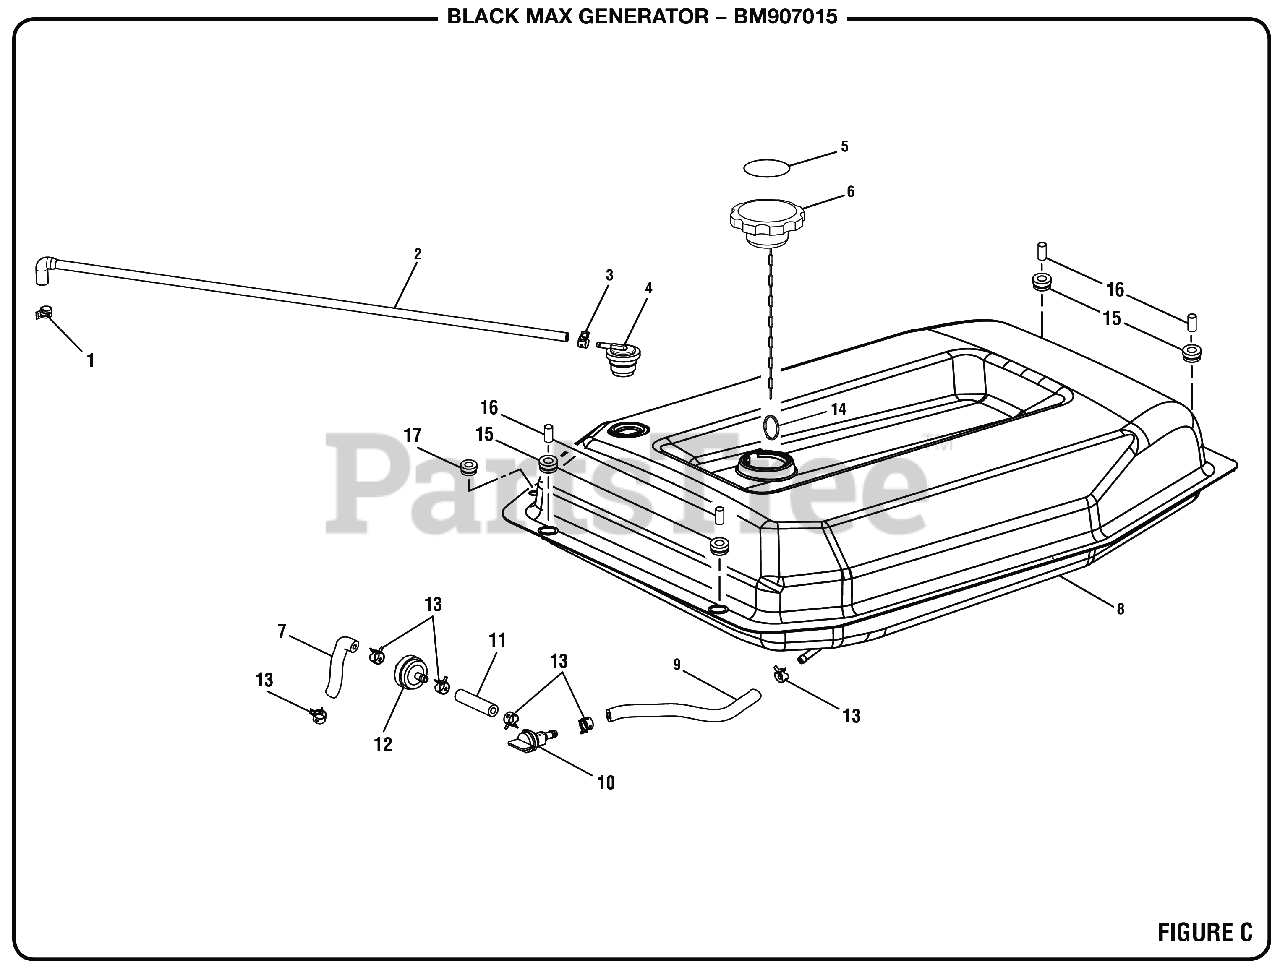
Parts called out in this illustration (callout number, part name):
1	Fuel Line Clamp (10.3 mm)
2	Vapor Hose (590 mm and 30 mm)
3	Fuel Line Clamp (3/8 in.)
4	Fuel Tank Vent Valve (PS905055SA)
5	Remove Cap Fuel Stabilizer Label (English)
6	Fuel Cap Assembly
7	Fuel Hose (185 mm)
8	Fuel Tank
9	Fuel Hose (175 mm)
10	Fuel Shut Off Valve
11	Fuel Hose (55 mm)
12	Fuel Filter Inline (1/4 in.)
13	Fuel Line Clamp (1/2 in.).
14	Ring Clip
15	Bushing (Fuel Tank Isolator)
16	Spacer (Fuel Tank Isolator)
17	Fuel Hose Protector
